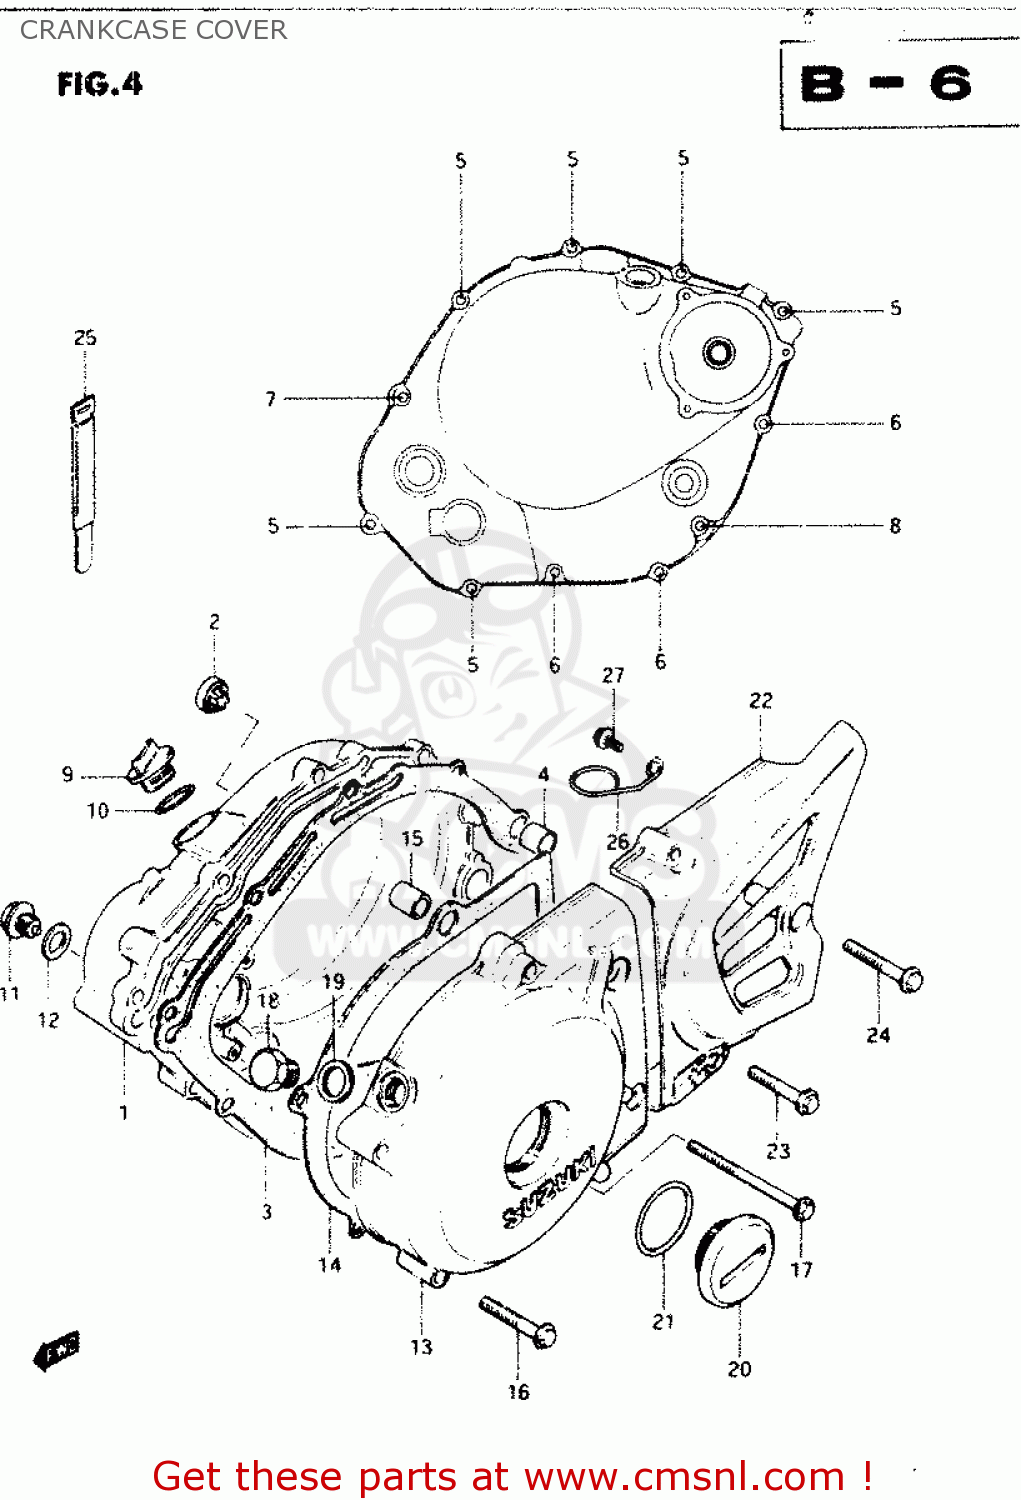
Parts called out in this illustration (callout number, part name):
1	COVER,CLUTCH
2	LENS,OIL LEVEL CHECK
3	GASKET,CLUTCH COVER (MCA)
4	PIN
5	BOLT (6X25)
6	BOLT (6X35)
7	BOLT (6X40)
8	BOLT (6X45)
9	PLUG
10	O RING(D:3.1,ID:16.8)
11	PLUG (14X12)
12	GASKET(14X19.2X2) (NAS)
13	COVER
14	GASKET
15	PIN
16	BOLT (6X35)
17	BOLT 6X50
18	PLUG(12X9)
19	GASKET(12.1X16.2X3.7) (NAS)
20	PLUG
21	O RING(D:3.1,ID:32.7)
22	COVER,SPROCKET
23	BOLT (5X30)
24	BOLT (5X35)
25	CLAMP L:110
26	GUIDE
27	BOLT
